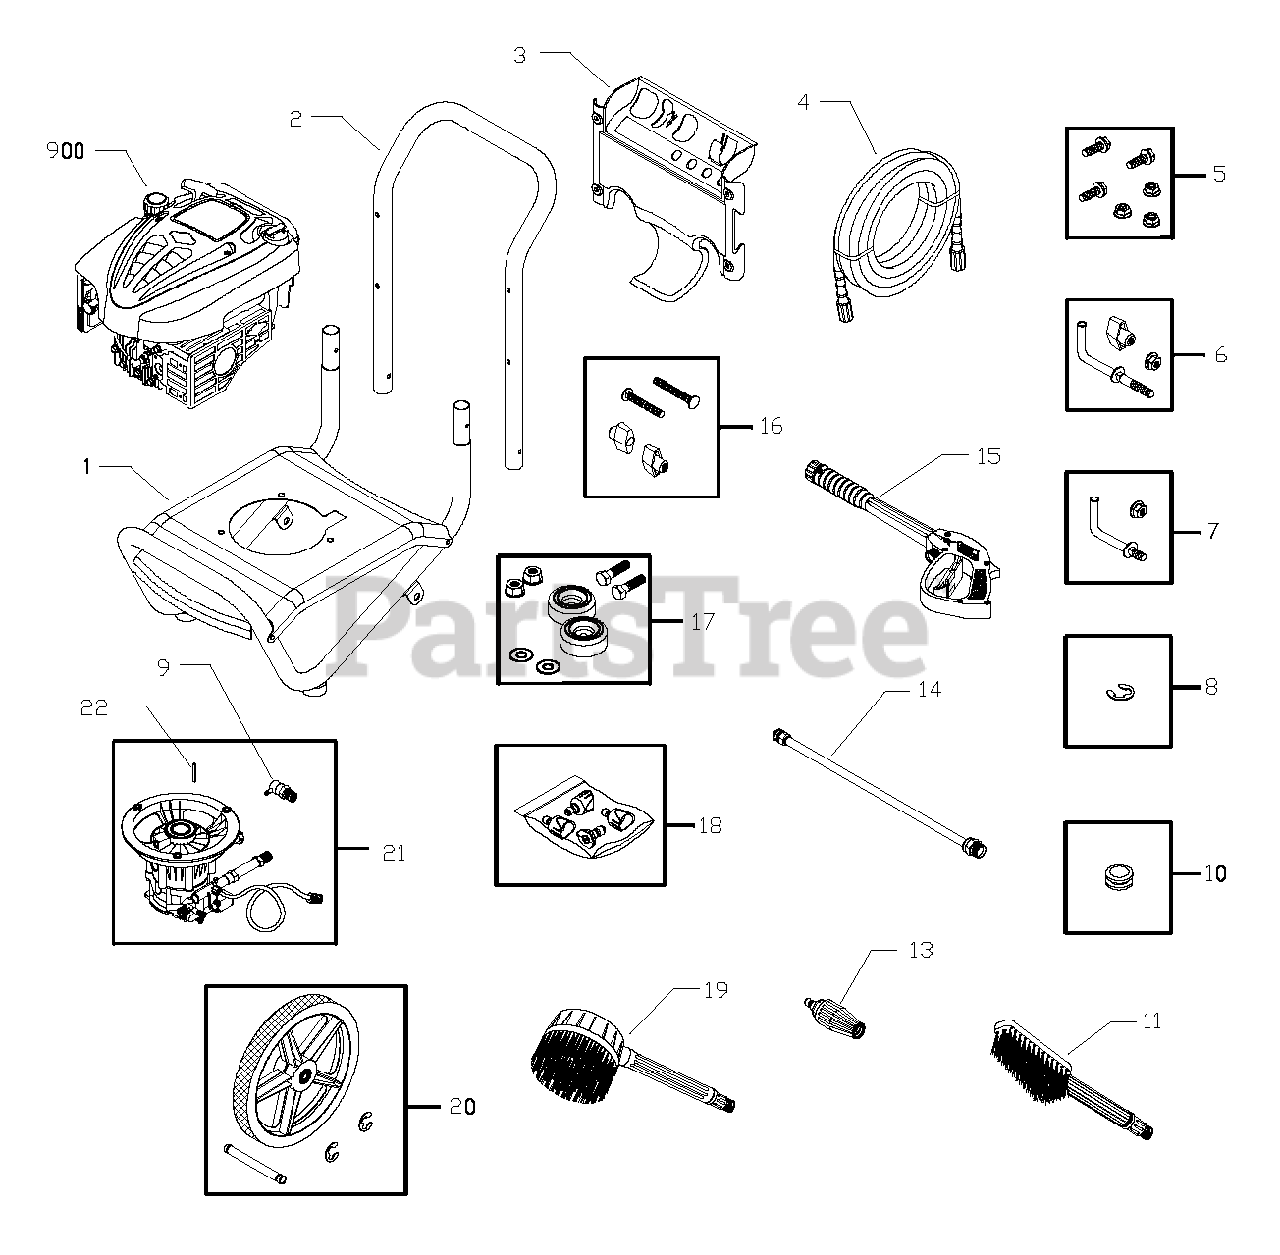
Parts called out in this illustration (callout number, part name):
3	ASSY, Billboard
4	HOSE
5	KIT, Pump Mounting Hardware
6	KIT, Hook, Handle
8	E-RING
9	VALVE,Thermal Relief
14	ASSY, Extension
15	GUN
16	KIT, Handle Connector
17	KIT,Vibration Mount
21	ASSY, Pump
900	ENGINE
